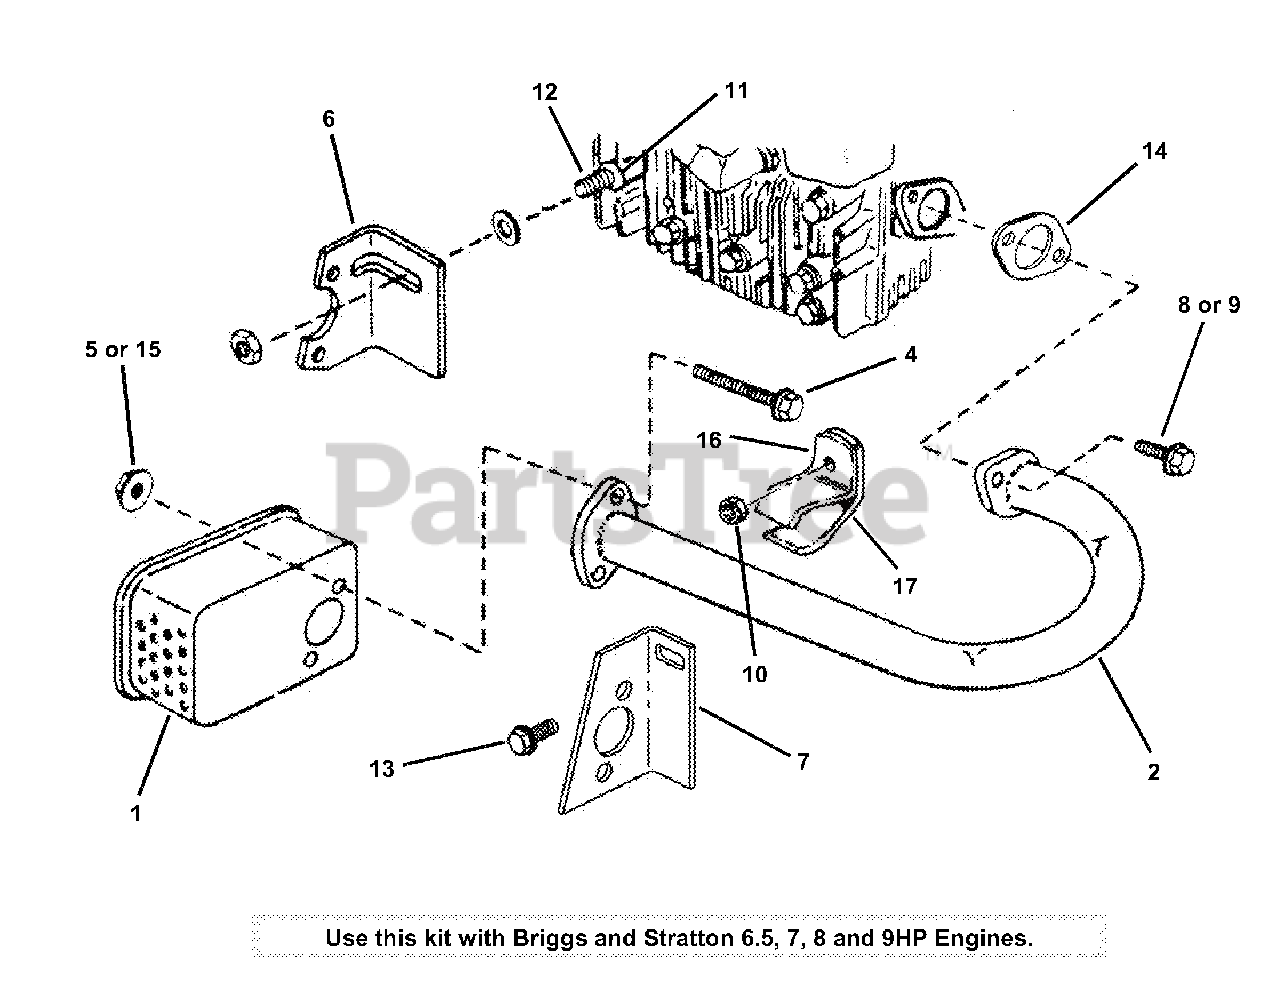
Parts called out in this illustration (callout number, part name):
1	MUFFLER, 8HP
2	TUBE, Exhaust
3	HARDWARE BAG
4	SCREW, 5/16-18 x 3" Hex Head Cap
5	NUT, 5/16-18 Hex Flange Lock
6	BRACKET, Muffler
7	BRACKET, Muffler
8	SCREW, 1/4-20 x 5/8" Hex Head Cap
9	SCREW, 5/16-18 x 3/4" Hex
10	NUT, 5/16-18 Hex
11	WASHER, 21/64" I.D. (Briggs #225137)
12	STUD, Cylinder Head
13	SCREW, 1/4-20 x 5/8" Hex Washer Self-Tap
14	GASKET, Exhaust
15	NUT, 5/16-18 Hex Center Lock
16	CLIP, Top
17	CLIP, Bottom
